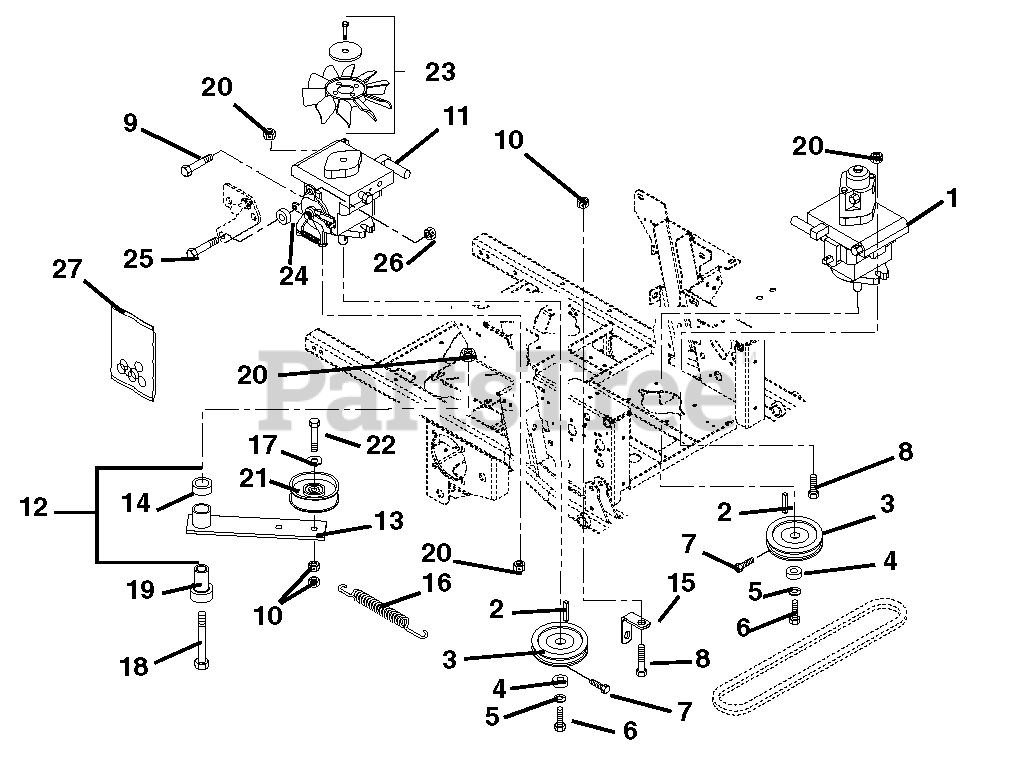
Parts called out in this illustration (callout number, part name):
1	Pump, Hydraulic with Auxiliary
2	Key, Square 5 x 5 x 30mm Plain
3	Sheave, Poly V .671 x 4.125
4	Washer, Flat Steel .281 x 1.000 x .063
5	Washer, Locking .25 x .062
6	Bolt, Hex M6 x 1.0 x 16
7	Screw, Socket Head .25-20 x .50 EP80
8	Bolt, Hex .50-13 x 1.50 Grade 5
9	Bolt, Hex .31-18 x .75 Grade 5
10	Nut-Locking-Top-Flange .38-16
11	Pump, Hydraulic BDP-21 with Thru Fan
12	Assembly, Idler Arm Guard Drive (Includes 13 & 14)
13	Weldment, Idler Arm Ground Drive
14	Bushing, 1.00 x 1.125 x 1.936
15	Anchor, Spring Idler
16	Spring, Extension
17	Washer, Flat Steel .39 x .75 x.125
18	Bolt, Hex .50-13 x 3.50 Grade 5
19	Bearing, Pedestal
20	Nut, Locking Top Flange .50-13
21	Idler, Flay 4.00 x .38
22	Bolt, Hex .38-16 x 2.25 Grade 5
23	Fan, Hydro Pump Cooling
24	Spacer .318 x .43 x .375
25	Bolt, Hex .31-18 x 1.25 Grade 5
26	Nut, Locking Top Flange .31-18
27	Kit, Pump Seal (BDP-21A)(One kit required for each pump)
